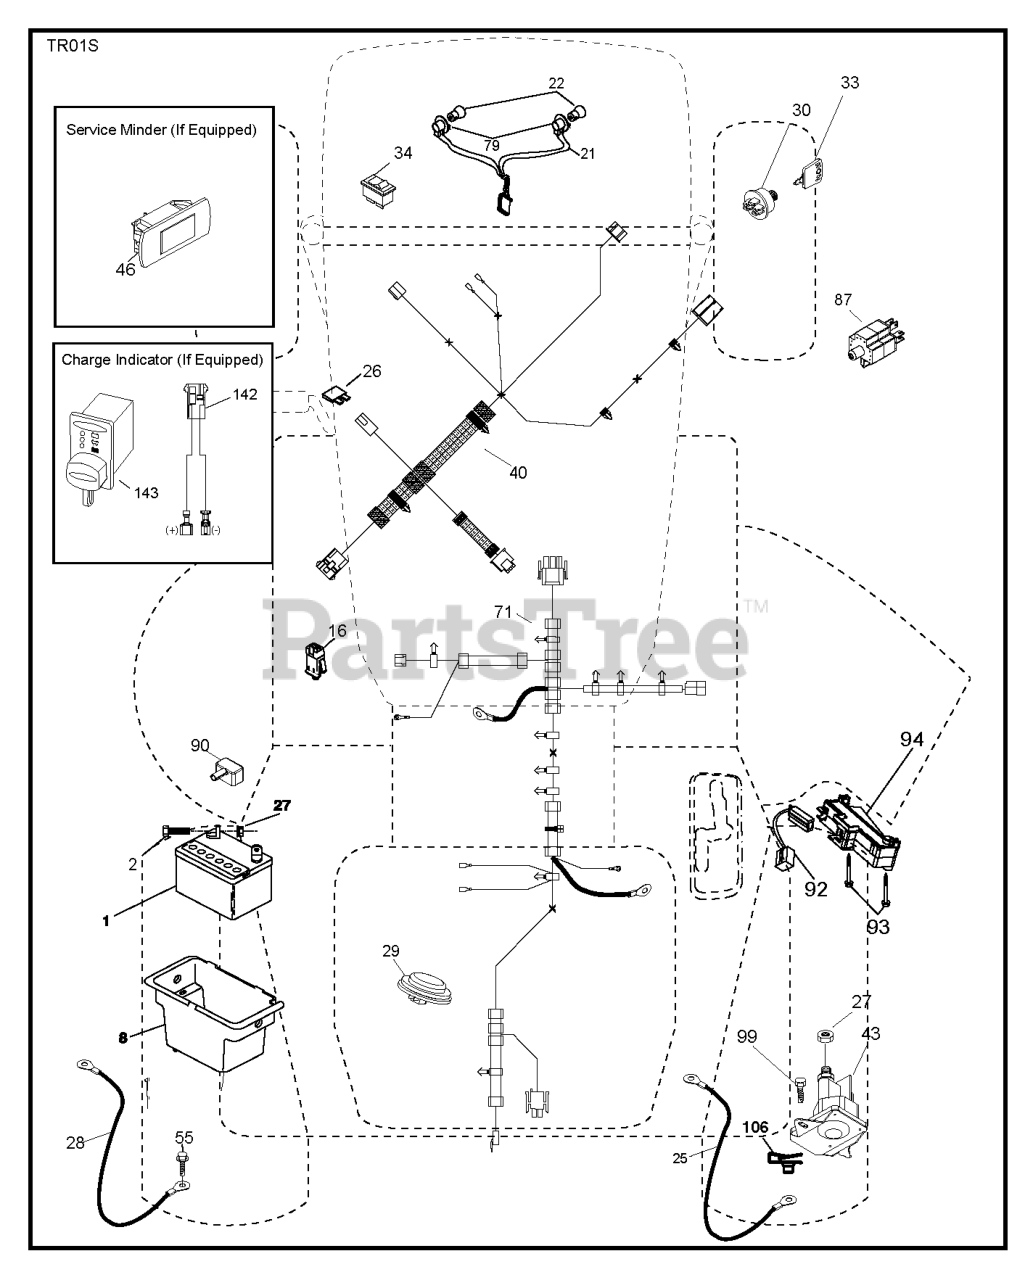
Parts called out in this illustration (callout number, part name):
1	Battery 12 Volt 25 Amp
2	BOLT.HEX.1/4.X.3/4.DICHROMATE
8	BOX.BATTERY.MNT.REAR.L
16	SWITCH INTERLOOK PUSH-IN
21	HARNESS.LIGHT W/4152J BULBS
21	HARNESS ASSY LIGHT
25	CABLE.BATT.RED.8GA.17
26	FUSE 20AMP
28	CABLE.GROUND.REAR.BATTERY.8G
29	SWITCH.SEAT.DELTA.OPC.
30	SWITCH.IGN.DELTA.W.LGH.ROS
33	KEY.CHAIN.BLISTER.PACK.GEN.USA
40	HARNESS.IGN.CHASS.TEX.REAR.BAT
40	HARNESS.TEX.DASH.MAN.REAR BATT
43	Solenoids
43	SOLENOID.W/BRASS.PLUNGER
46	GUAGE.SRVCMNDR.HRMTR.
55	SCREW 5/16"
71	HARNESS IGN. DASH
71	HARNESS.CHASSIS.RRBATT.RDYSTRT
79	BULB HOLDER ASM.
87	SWITCH.INTRLCK.CLUTCH.
90	COVER.TERMINAL.BATTERY
92	HARNESS.PIGTAIL.CONSLE
94	MODULE.REVERSE.ROS
99	SCREW HEXWSHR 1/4-20X3/4
106	1/4-20 U NUT
